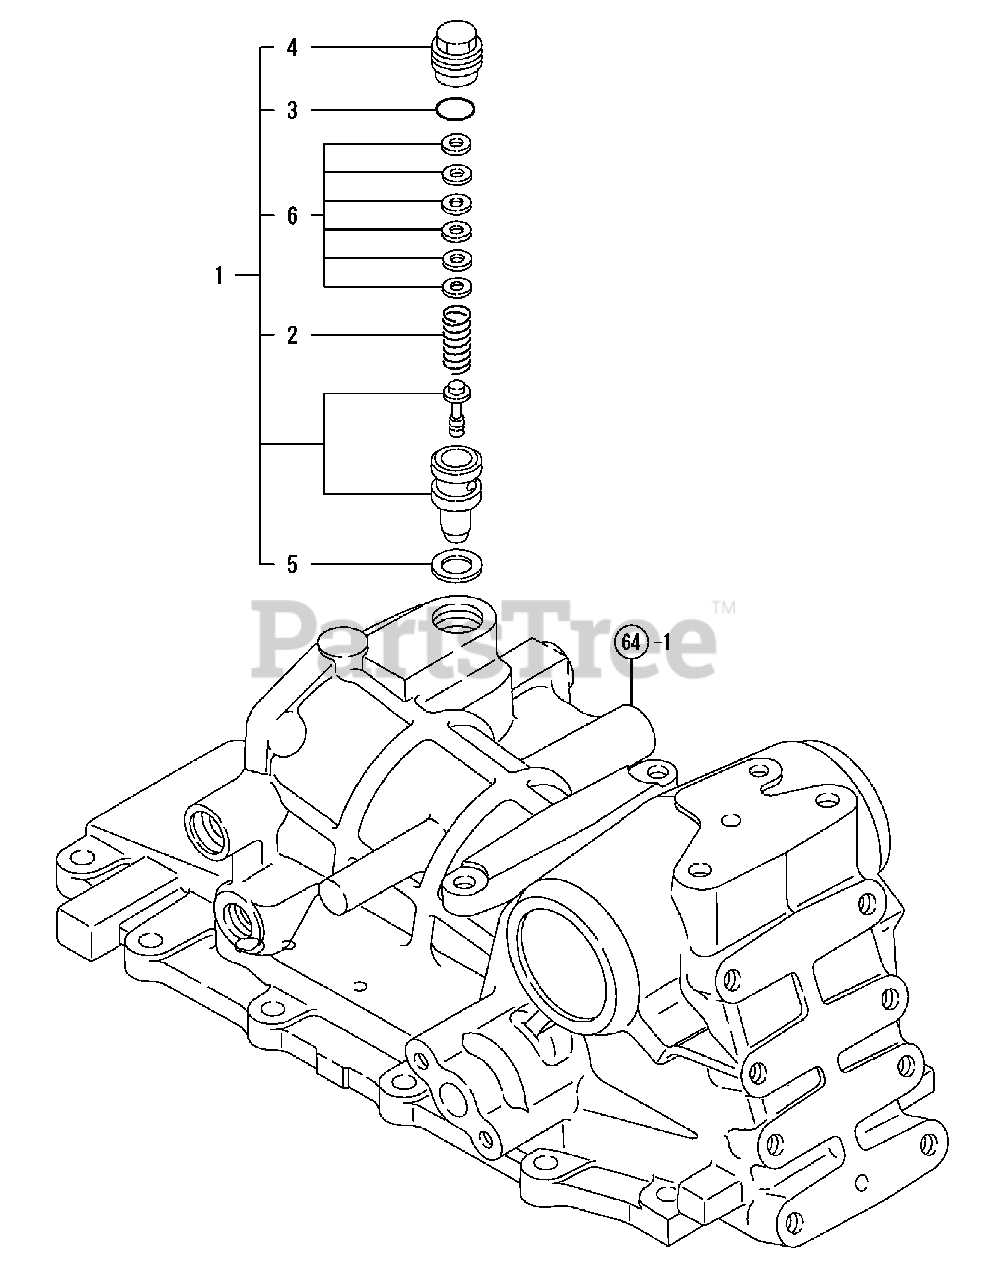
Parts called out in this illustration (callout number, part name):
1	VALVE ASSY, RELIEF
4	PLUG, RELIEF VALVE
5	GASKET 20X27.8X2
